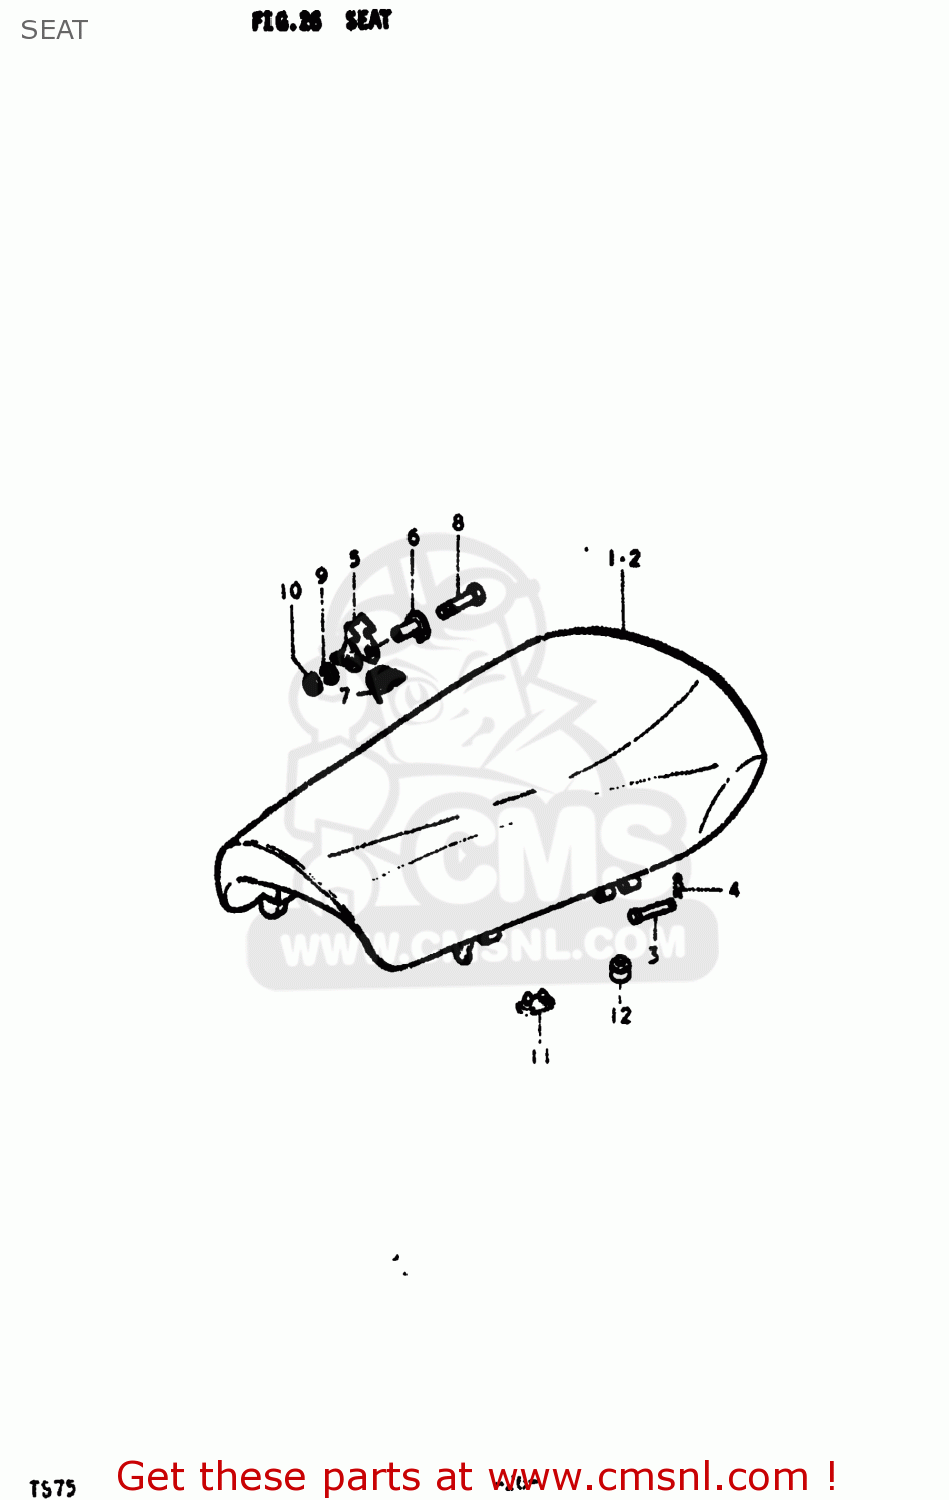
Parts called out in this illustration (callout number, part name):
1	SEAT ASSEMBLY
2	SEAT ASSEMBLY
3	PIN
4	CLIP
5	STRIKER,SEAT LOCK
6	STRIKER,SEAT LOCK
7	SPRING
8	BOLT 8X40
9	LOCK WASHER
10	NUT
11	CUSHION
12	CUSHION
